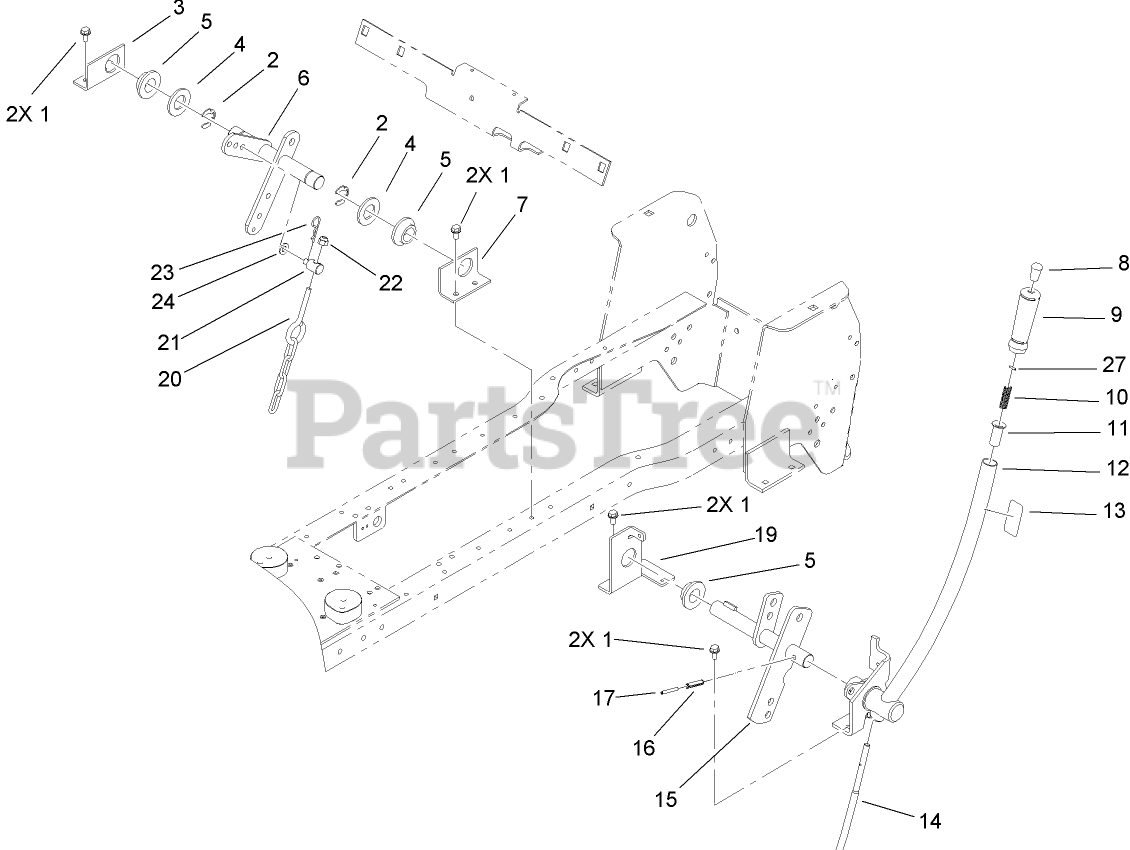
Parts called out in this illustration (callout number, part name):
1	SCREW-HWHTF
2	RING-RETAINING
3	BRACKET-PIVOT LINKAGE, RH
4	WASHER-FLAT
5	BEARING-FLANGE
6	LIFT LEVER ASM
7	BRACKET-PIVOT LINKAGE, LH
8	TIP-ROD
9	GRIP-HANDLE
10	SPRING-COMPRESSION
11	RETAINER-SPRING
12	LIFT LEVER ASM
13	DECAL-LIFT
14	ROD-LEVER, LIFT
15	LIFT ARM ASM
16	PIN-ROLL
17	PIN-SPRING
19	BRACKET-PIVOT, LIFT
20	CHAIN-LIFT
21	TRUNNION
22	NUT-LOCK, NI
23	PIN-HAIR
24	WASHER-FLAT
27	PIN-SPIROL
